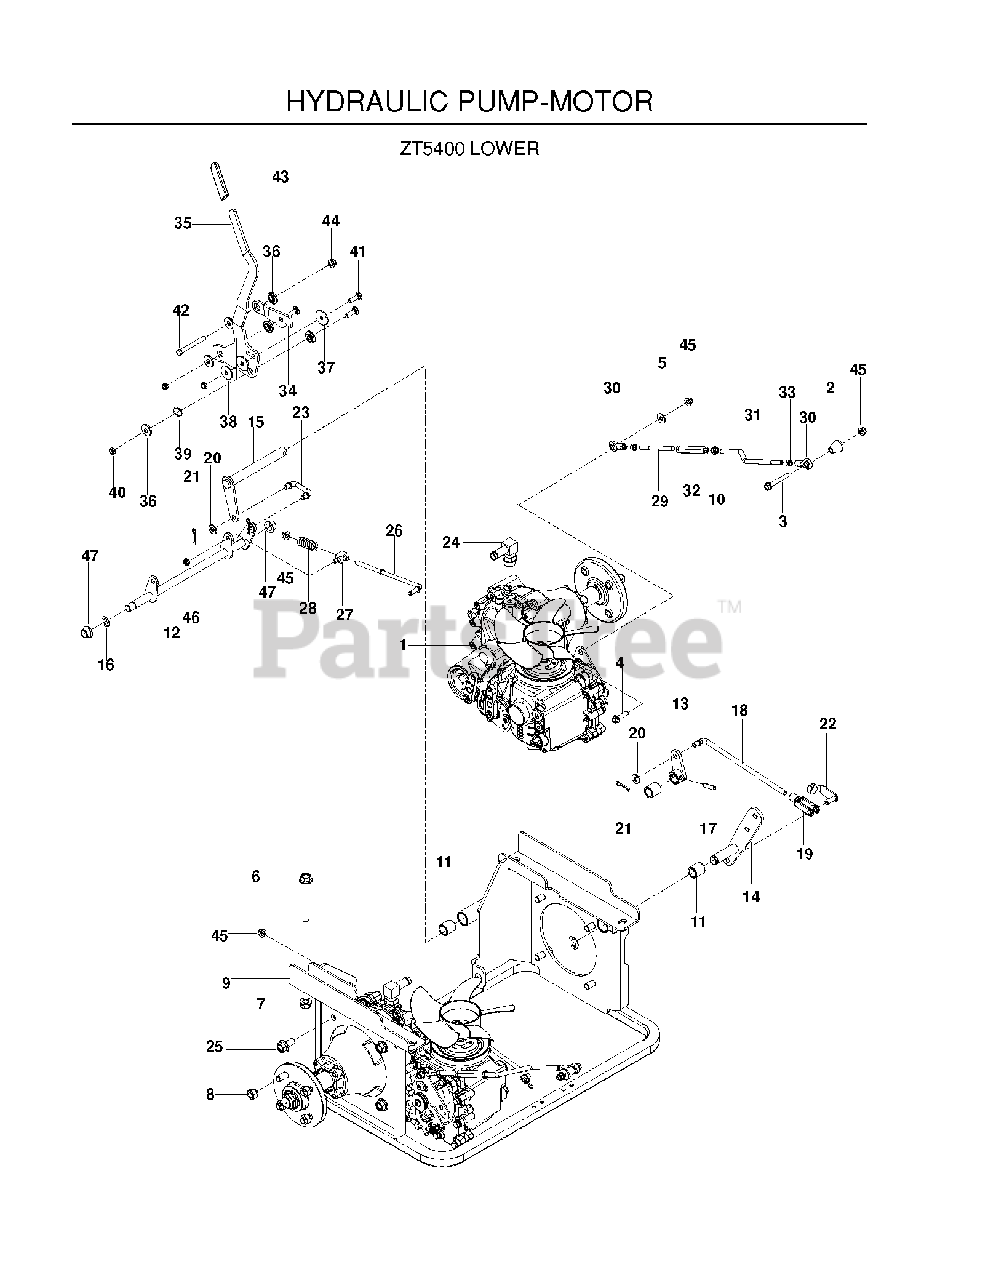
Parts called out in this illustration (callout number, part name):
3	HHFS 5/16-18 X 2.25 GD 5
4	HHFS 5/16-18 X 1.25 TPBLT GD 5
5	WASHER 5/16 FLAT
6	HHFS 1/2-13 X 4.0 GD8 ZD
7	NUT, 1/2-13 HEX FLG NYLOC ZD
8	LUG NUT 1/2F
10	NUT 3/8-24 JAM
11	BUSHING, SLEEVE 3/4 X 1.0
13	ARM, RT BRAKE
16	E RING 3/4
17	5/16 DIA ROLL PIN
20	WASHER 3/8 SAE FLAT
21	HAIRPIN #2
22	PIN, CLEVIS SPRING, 3/8
25	HHFS 1/2-13 X 1 GR5 ZD
27	SWIVEL, BRAKE
29	LINKAGE, CONTROL, FT
30	BALL JOINT, RIGHT HANDED
32	TURNBUCKLE, 3/8
33	NUT 5/16F
34	LINK, FOLLOWER
35	LEVER, BRAKE, BLK
36	BUSHING, BRAKE
37	WASHER, FRICTION, 1/8
38	CONE WASHER
39	WASHER, .825 X 1.087, WAVE
40	NUT HEX 3/8-16 NYLON, THIN
41	RHSNB 3/8-16 X 1-1/4
42	HCS 3/8-16 X 3-1/4 GR5 ZD
44	NUT 3/8-16 HEX FLG NYLOC ZD
45	5/16-18 NYLOC FLANGE NUT
46	5/16-18 THIN PROF NY
